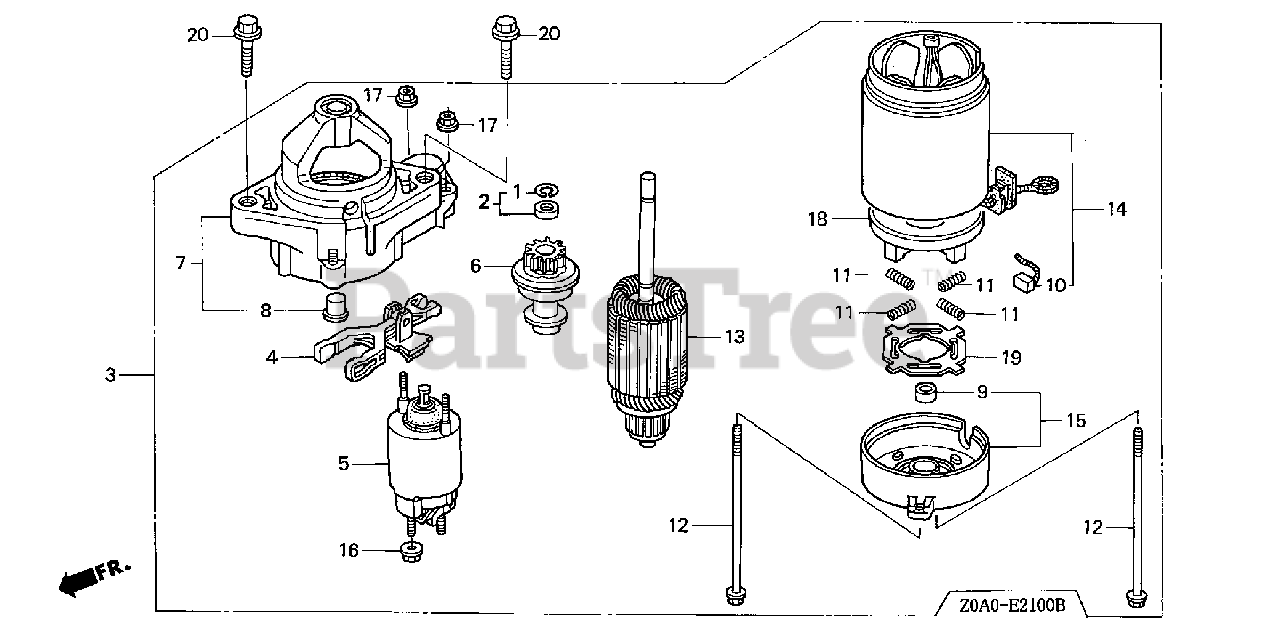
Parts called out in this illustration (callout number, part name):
1	RING, SNAP (DENSO)
2	COLLAR SET, CLUTCH STOP
3	MOTOR ASSY., STARTER
4	LEVER, PINION DRIVE
5	SWITCH ASSY., MAGNETIC
6	CLUTCH, OVERRUNNING
7	HOUSING, DRIVE SIDE
8	BEARING A
9	BEARING B
10	BRUSH
11	SPRING, BRUSH
12	BOLT, THROUGH
13	ARMATURE
14	YOKE
15	FRAME, COMMUTATOR END
16	NUT, HEX. (8MM)
17	NUT, FLANGE (5MM)
18	HOLDER, BRUSH
19	INSULATOR, BRUSH HOLDER
20	BOLT, FLANGE (10X40)
